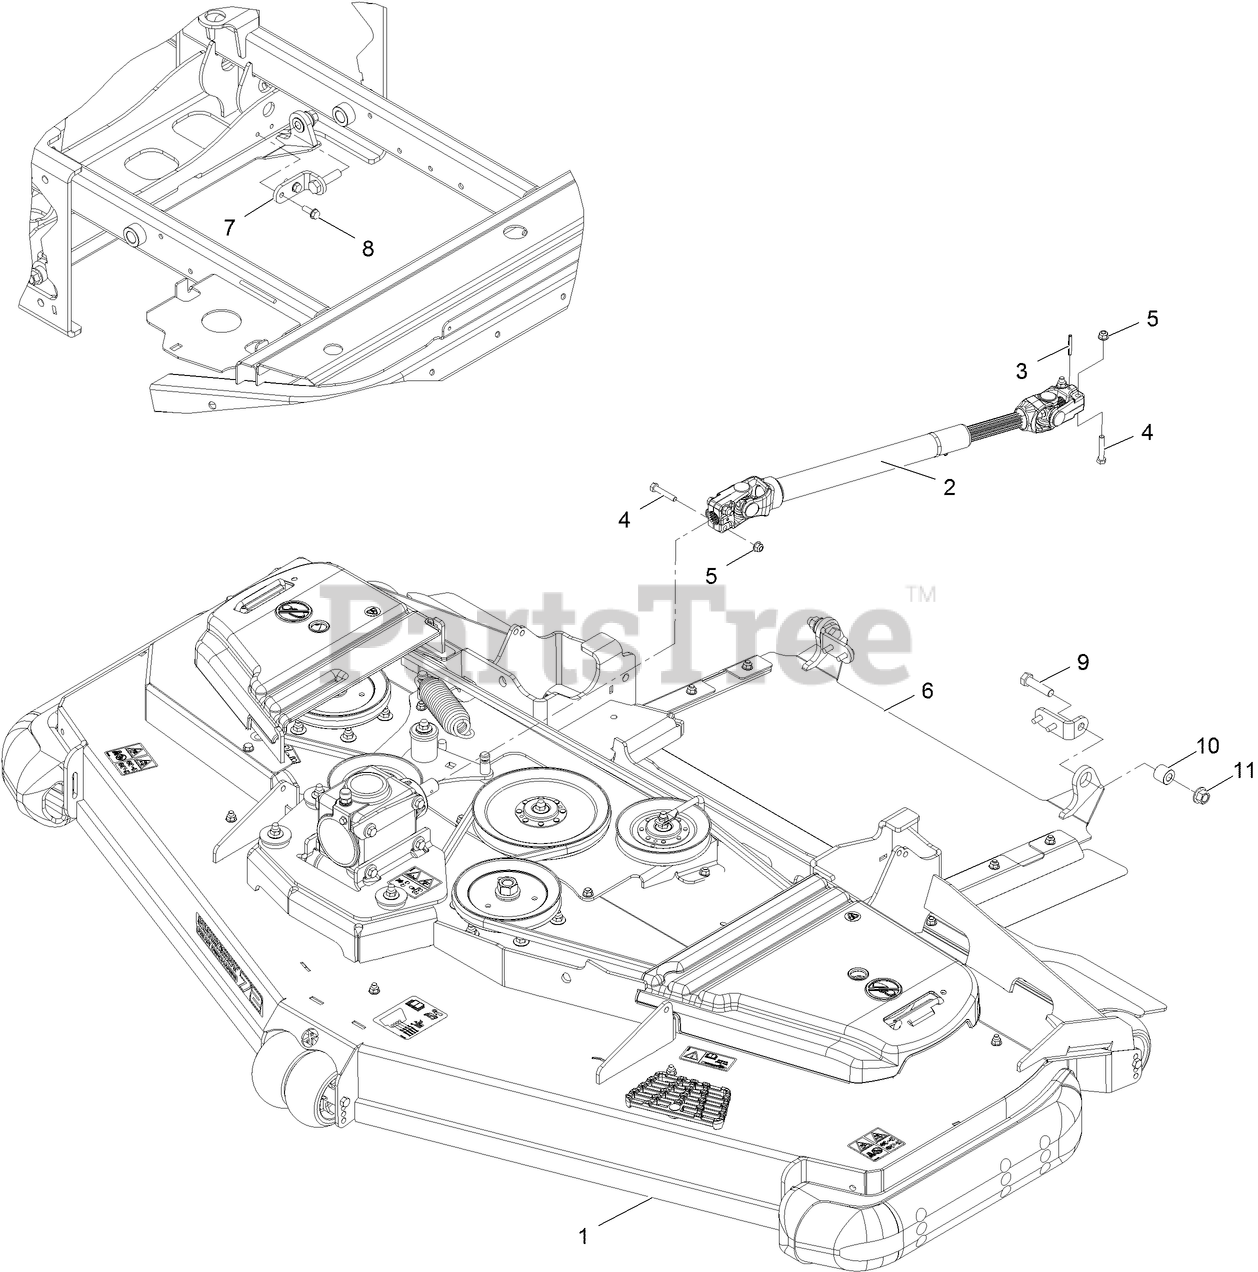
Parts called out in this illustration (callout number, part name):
1	Deck ASM-72Rd
2	DRIVESHAFT ASM
3	PIN-ROLL
4	SCREW-HH
5	NUT-HF, NI
6	Discharge Tunnel ASM
7	BRACKET-DISCHARGE
8	SCREW-TAPTITE
9	SCREW-HH
10	BUSHING-SLEEVE
11	Nut-Lock 1/2-13
